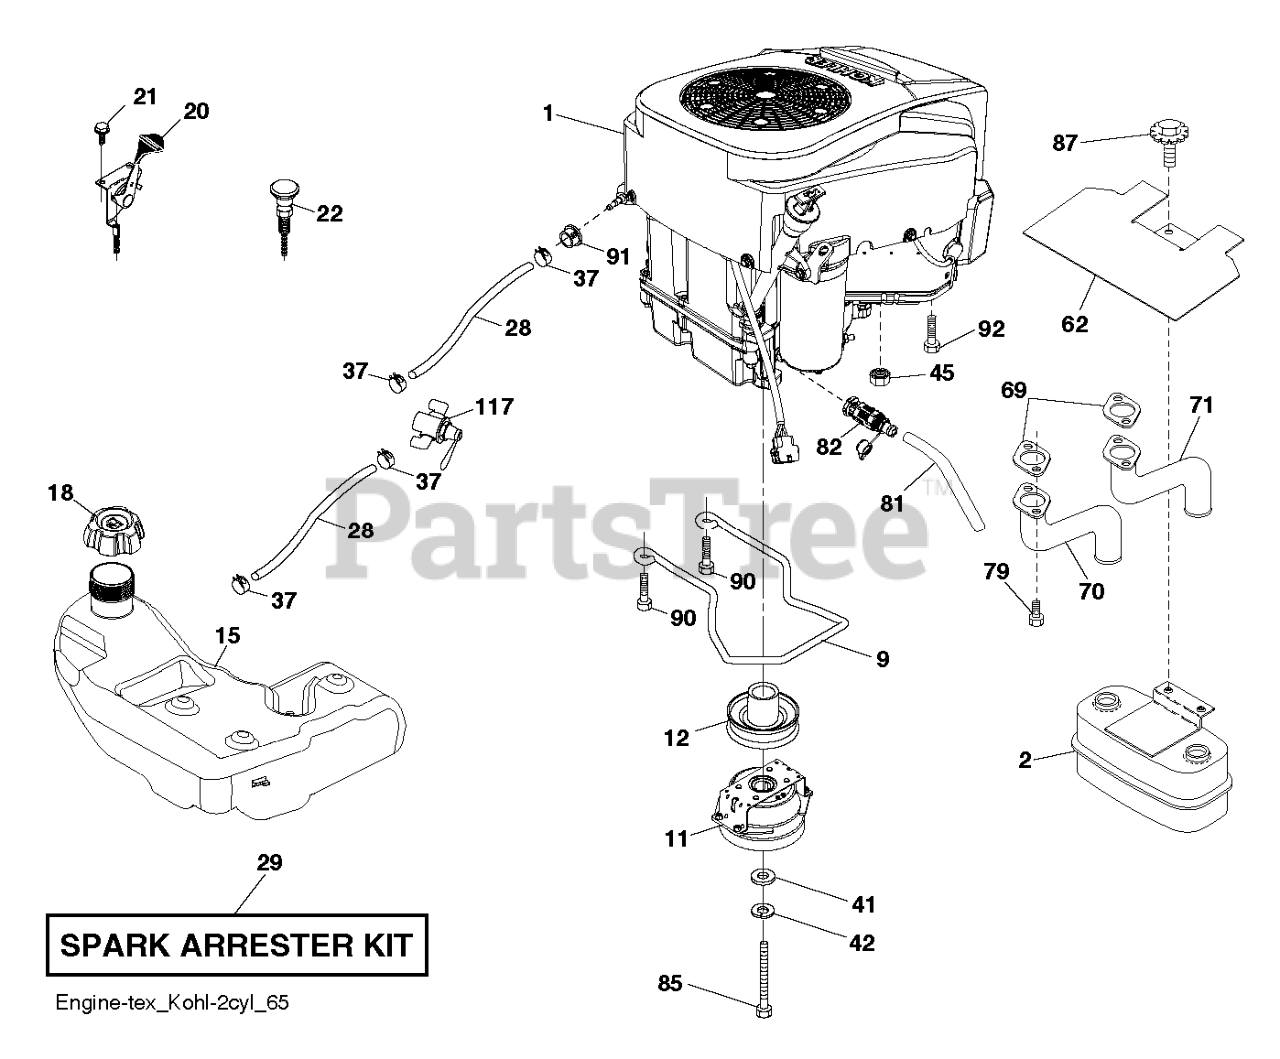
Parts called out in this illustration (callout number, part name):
2	MUFFLER.ASM.TWN.EXTNDED.DFLCTR
9	KEEPER BELT ENGINE
11	CLUTCH.OGURA.5.0PD.GT1.5A-EH01
12	PULLEY ENGINE
15	RP_TANK.ASSY.4.GAL.2.PORT.EPA
18	CAP ASSY FUEL 3" BLACK
20	THROTTLE CONTROL
21	SCREW.#10 X 0.750.BOS
22	CONTROL.CHOKE.ERGO.PUSH-IN.BLA
28	LINE.FUEL.64"REAR.EMIS
29	KIT.SPARK ARRESTOR 794945 B&S
37	HOSE CLAMP
42	LOCKWASHER
45	NUT
62	SHIELD.HEAT.MUFFLER
69	GASKET.EXHAUST.KOHL.CV18-CV26
70	SCREW.SOCKET HD.5/16-1
71	PIPE.EXHAUST.RH.CV18/20
79	SCREW.SOCKET HD.5/16-1
81	TUBE, DRAIN OIL ASM.
82	VALUE.OIL.DRAIN
84	SCREW 3/8-16X1
85	BOLT.HEX.7/16-20X3.0XGR5
87	BOLT.5/16-18UNCX1.W/SEMS.BLK
90	SCREW 3/8-16X1
91	BUSHING.1.375OD
117	VALVE FUEL RESERVE
